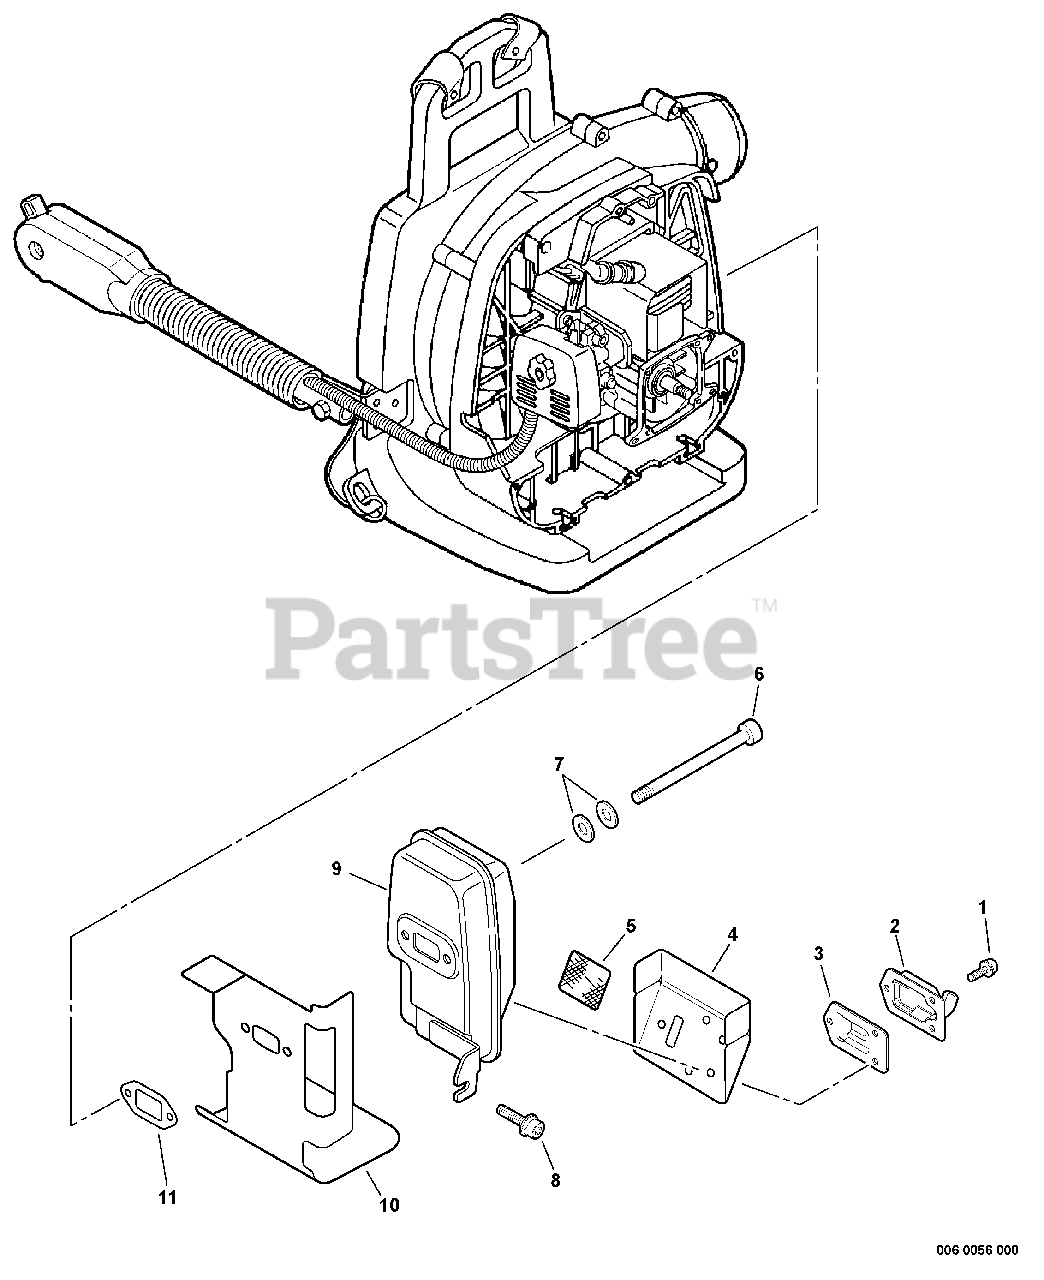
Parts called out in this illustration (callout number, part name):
1	SCREW 4×10
2	GUIDE, EXHAUST
3	GUIDE, EXHAUST
4	GASKET, EXHAUST
5	SCREEN, SPARK ARRESTER
6	BOLT 5×60
7	WASHER, FLAT 5.5×10×0.8
8	BOLT 5×16
9	MUFFLER
10	HEAT SHIELD, EXHAUST
11	GASKET, EXHAUST
